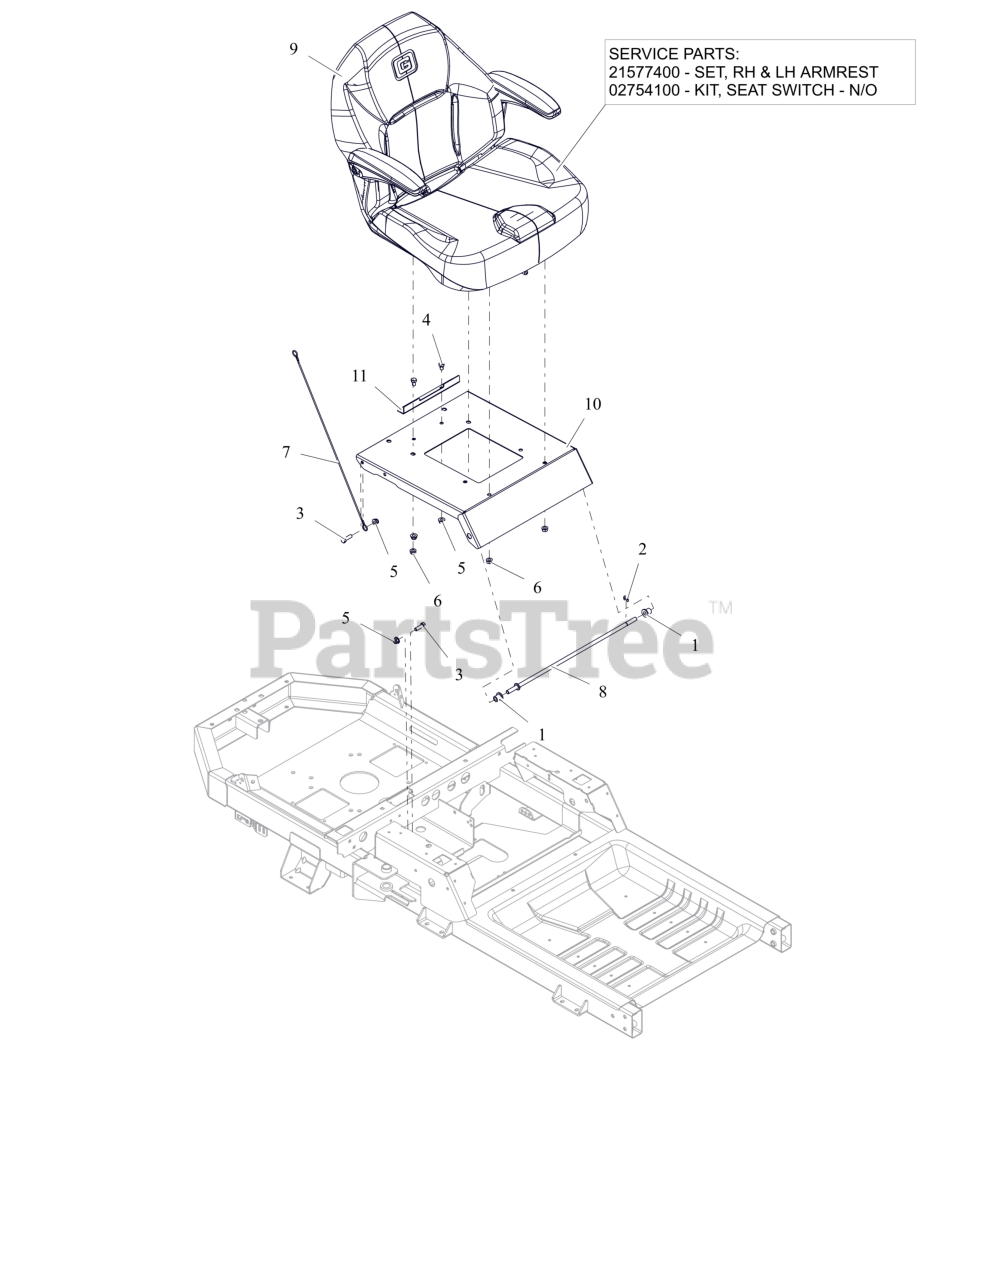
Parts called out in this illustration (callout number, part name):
1	BSHG-FLG .38X.580X.667X.750
2	RG-RTNG-EXT .375X.035 TYP E
3	BLT,HEX .31-18X1.00 G5 ZCC
4	BLT, HEX .31-18X.50 GR5 ZCC
5	NUT,NYL-FLG .31-18 GF ZCC
6	NUT,LK-CTR-FLG .31-18 GF ZCC
7	LANYARD, SEAT CABLE .093X19.5
8	ROD- SEAT PIVOT
9	SEAT- ZTX SPECIAL EDITION
9	SET, RH & LH ARMREST
9	SWITCH- SNAP MTG N.O.
10	PLATE- SEAT - LIMITED
11	STOP- SEAT SLIDE
